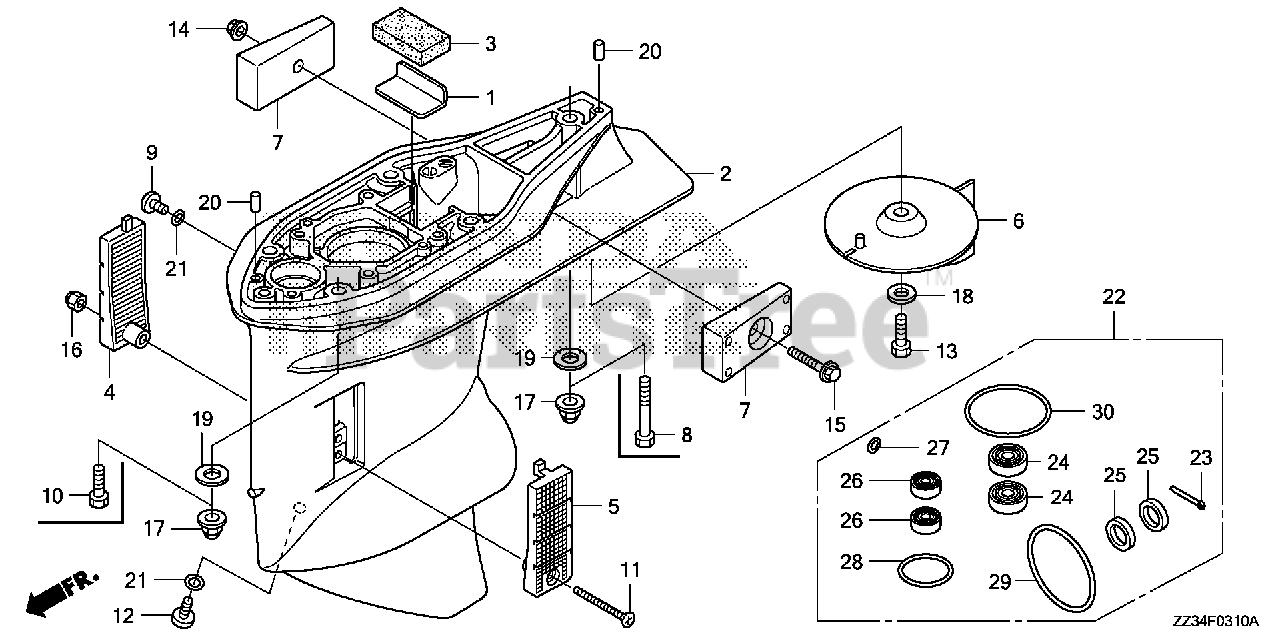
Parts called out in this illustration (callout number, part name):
1	PLATE, RUBBER SETTING
2	CASE, GEAR *NH282MU* (OYSTER SILVER METALLIC-U)
3	GROMMET, GEAR CASE
4	SCREEN, R. WATER
5	SCREEN, L. WATER
6	TAB, TRIM *NH282MU* (OYSTER SILVER METALLIC-U)
7	METAL, ANODE
8	BOLT, HEX. (10X60)
9	BOLT, OIL CHECK
10	BOLT, HEX. (10X32)
11	SCREW, FLAT (5X37)
12	BOLT, DRAIN PLUG
13	BOLT, HEX. (8X20)
14	NUT, SELF-LOCK (6MM)
15	BOLT, FLANGE (6X30)
16	NUT, SELF-LOCK (5MM)
18	WASHER, PLAIN (8MM)
19	WASHER, PLAIN (10MM)
20	PIN, DOWEL (6X10)
21	O-RING (6.9X1.45)
22	CASE KIT, GEAR
23	PIN, SPLIT (4.0)
24	SEAL, WATER (17X36X6)
25	SEAL, WATER (22X35X7)
26	SEAL, WATER (12X21X6)
27	O-RING (6.9X1.45)
28	O-RING (33.7X3.5)
29	O-RING (76.5X3)
30	O-RING (58.5X3.5)
